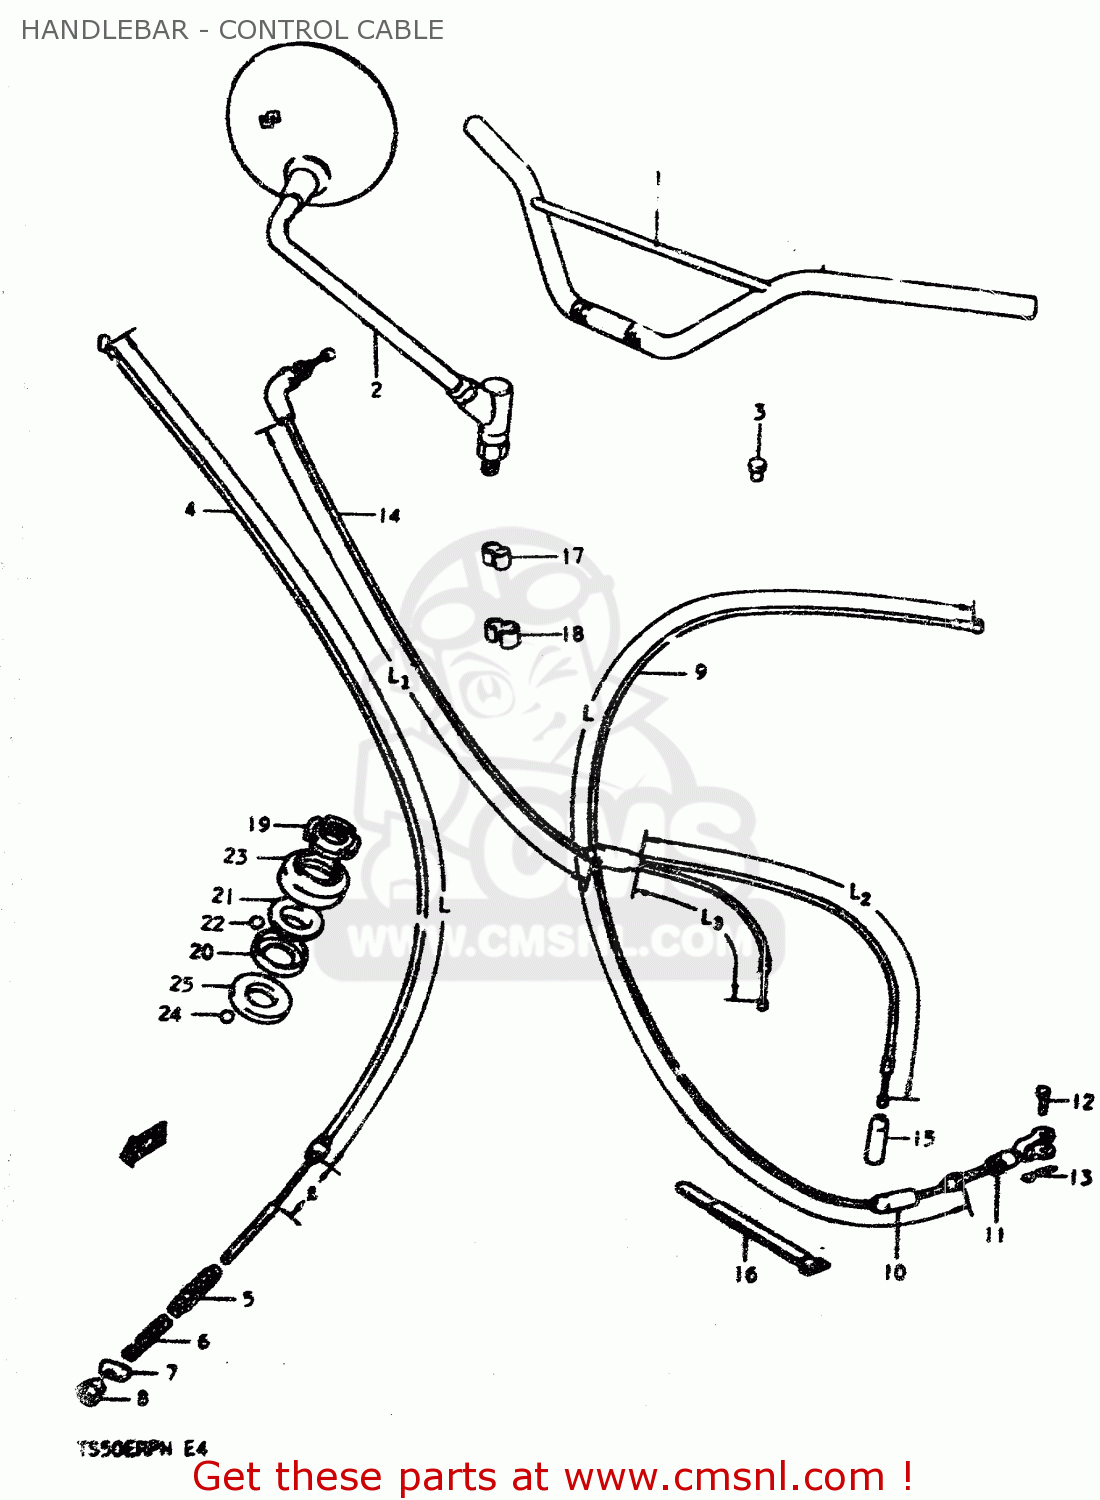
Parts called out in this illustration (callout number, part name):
1	HANDLEBAR
2	MIRROR ASSY, REAR VIEW RH
3	CAP
4	CABLE ASSY, BRAKE
5	SEAL,DUST(7X16X75)
6	SPRING
7	PIN,10X19
8	NUT
9	CABLE ASSEMBLY,CLUTCH
10	SEAL,DUST(7X18X30)
11	NUT 8MM
12	PIN(L:13)
13	PIN
14	CABLE ASSY, THROTTLE
15	SEAL,DUST(7X18X30)
16	CLAMP
17	CLIP
18	CLIP
19	NUT,STEERING STEM(25X44X10)
20	RACE, INNER UPPER
21	RACE,STEERING OUTER UPR
22	BALL
23	DUST SEAL,STEERING UPR
24	BALL
25	LACE,STEERING INNER LWR
